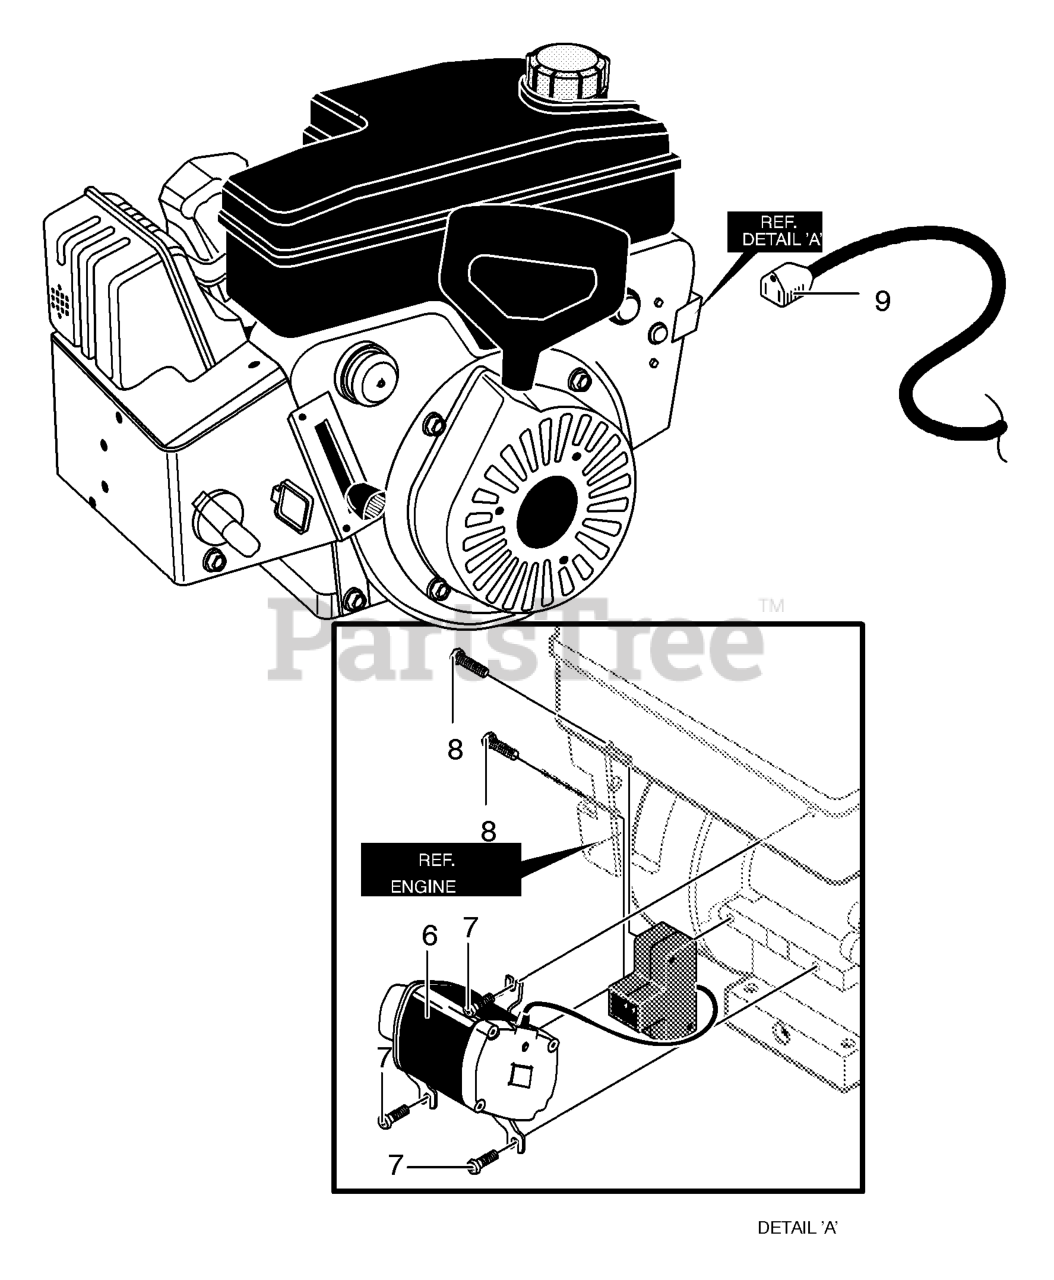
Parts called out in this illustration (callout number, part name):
6	MOTOR, STARTER
8	SCREW
9	CORD, Electric, 10FT. 110V
